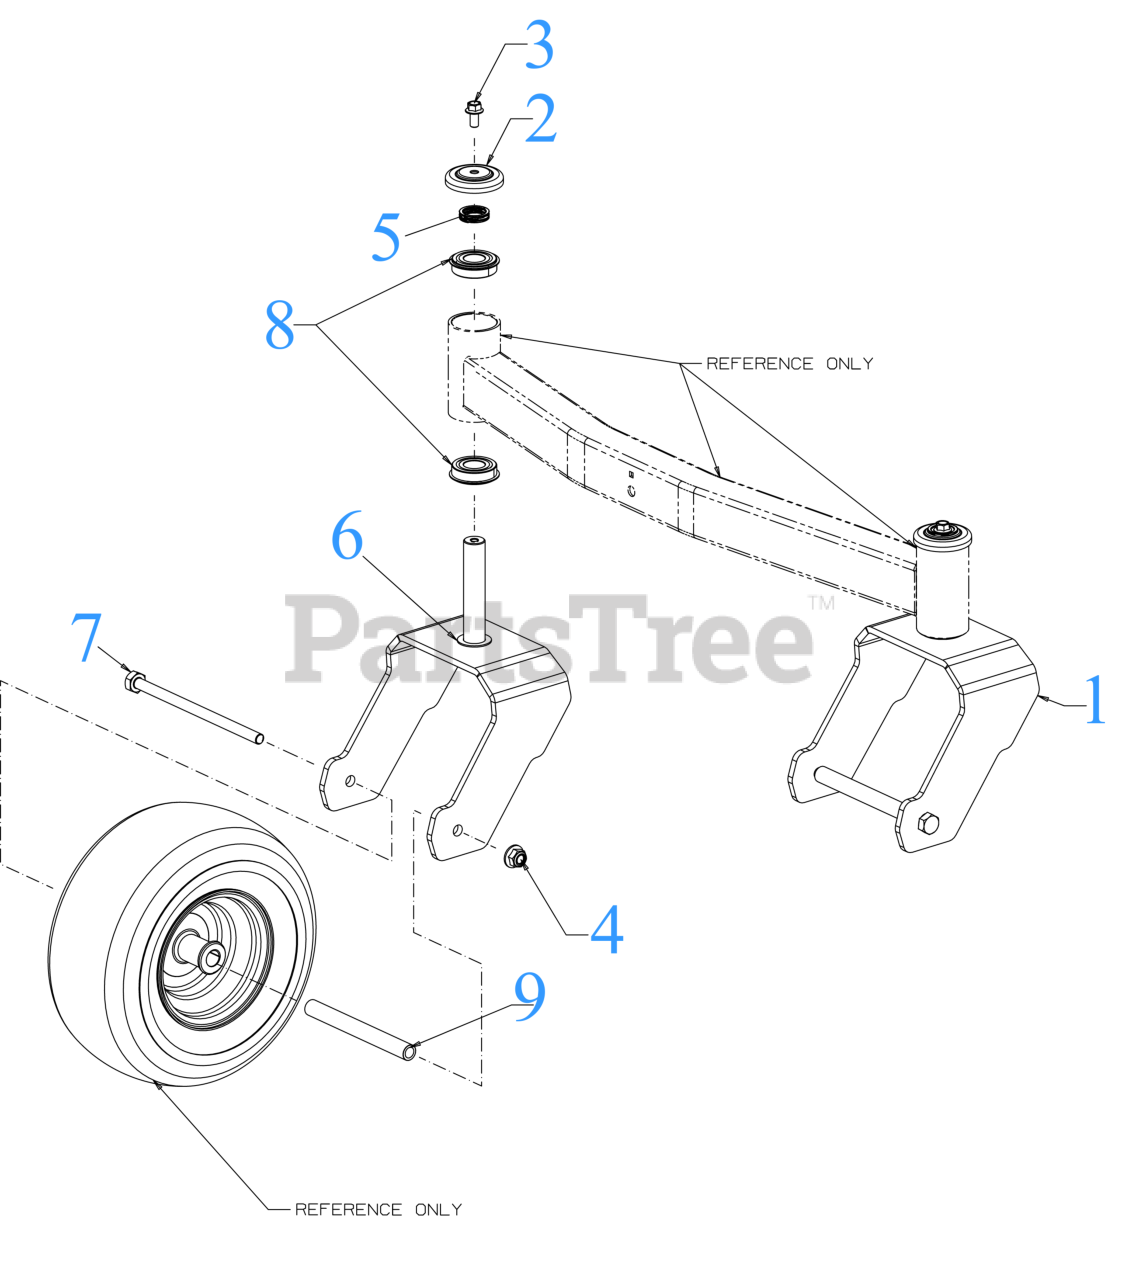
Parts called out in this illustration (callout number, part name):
1	CASTER WHEEL YOKE
3	BOLT - 3/8-16:.75:GR5:PATCH LOCK
5	WAVE WASHER
6	WASHER 1.010X1.560X.060
7	SCREW-1/2-13X8.5 GR5 FLG RZF-SX
8	BALL BEARING 25X52X15
9	CASTER AXLE SPACER
